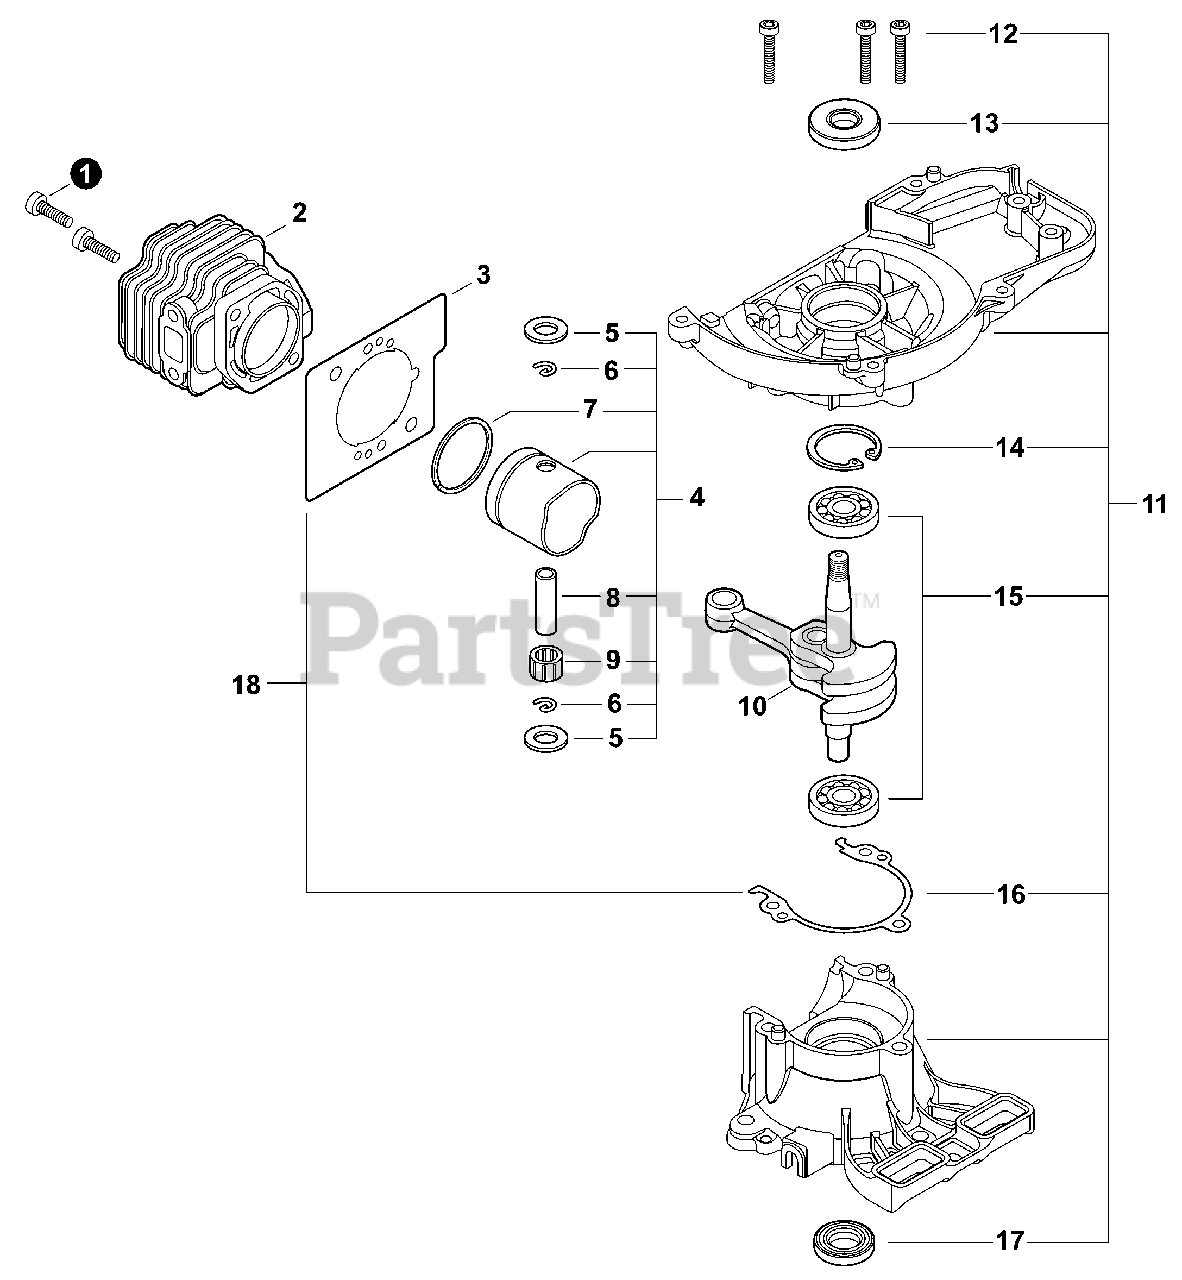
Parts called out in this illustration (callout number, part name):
1	BOLT, TORX 5×20
2	CYLINDER
3	GASKET, CYLINDER
4	PISTON KIT
5	WASHER, THRUST
6	RING, SNAP
7	RING, PISTON
8	PIN, PISTON 8
9	BEARING, NEEDLE
10	CRANKSHAFT ASSY
11	CRANKCASE ASSY
12	BOLT, TORX 5×25
13	SEAL, OIL
14	RING, SNAP 26
15	BEARING, BALL
16	GASKET, CRANKCASE
17	SEAL, OIL
18	GASKET KIT
